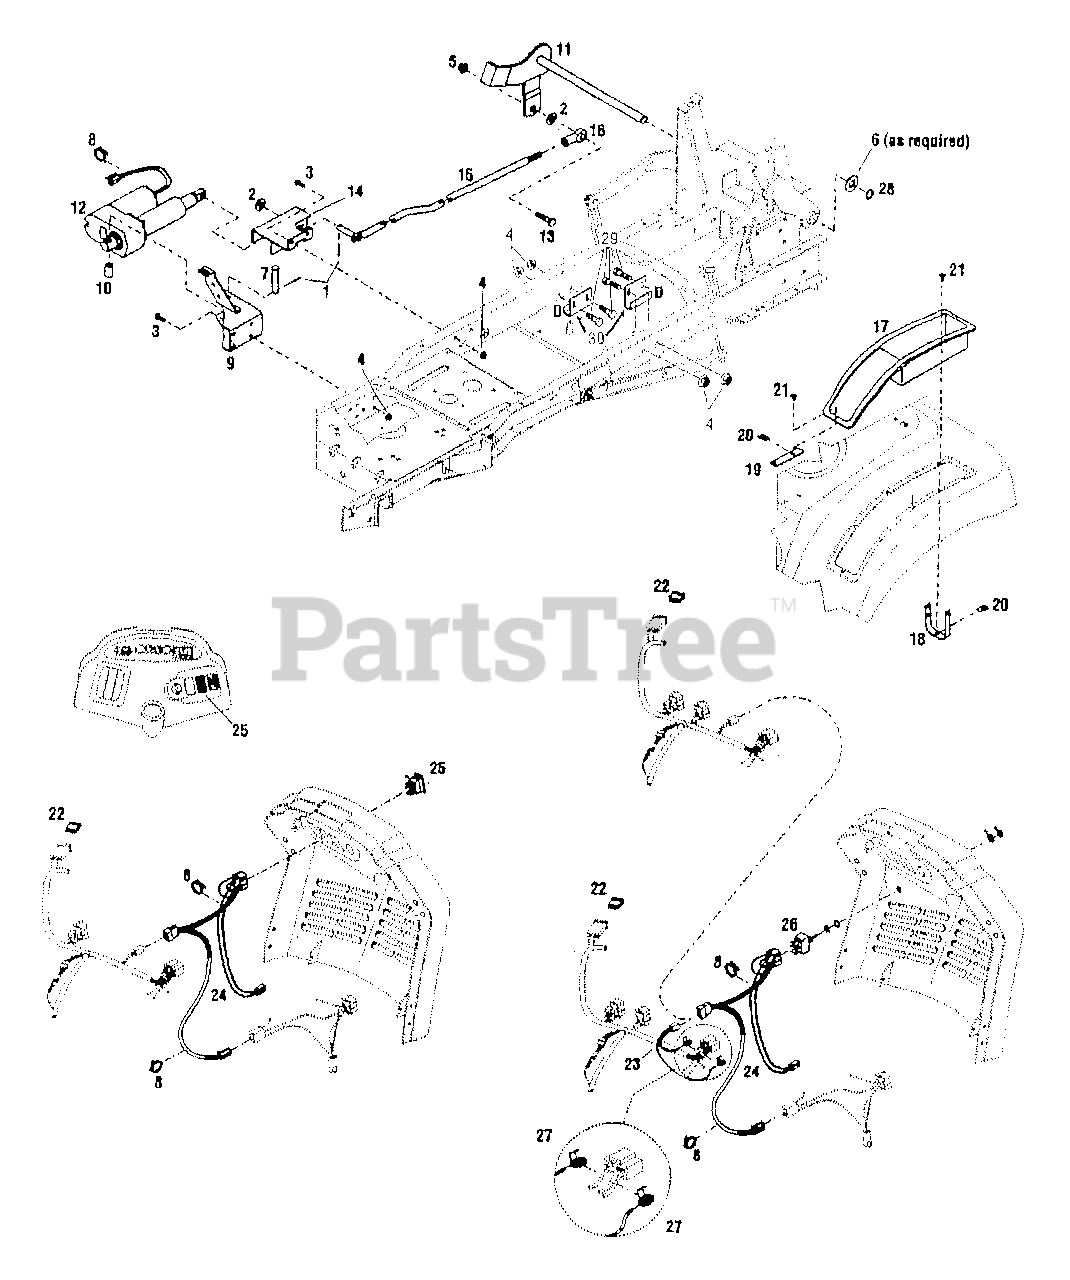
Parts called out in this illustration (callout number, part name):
1	PIN-COTTER .120X1.00 ZP
2	WASHER-1.06X.531X.1 ZP
3	SCR-HFLK 5/16-18X.75 ZP
4	NUT-HFLK 5/16-18 ZP
5	NUT-TOP LOCK 1/2-13 ZP
6	WASHER-1.25X.765X.049
7	PIN-CLEVIS .5X2.75
8	TIE-CABLE NYLON BLACK
9	SUPPORT-FRONT
11	PIVOT LIFT ARM ASSY.
13	SCR-SPECIAL 1/2-13X1 1/2
14	SUPPORT-REAR
15	ROD-LIFT
16	ROD-END
17	UTILITY BOX
18	RETAINER-UTILITY BOX
19	RETAINER-UTILITY BOX
20	SPEED NUT-1/4-20
21	SCR-1/4-20X5/8
22	FUSE-30 AMP
23	ADAPTER HARNESS
24	HARNESS-ACTUATOR
25	SWITCH-ROCKER
26	SWITCH-TOGGLE
27	CONNECTOR
28	RETAINING RING
29	SCR-HHC 5/16-18X.75 GR 5 ZP
30	STOP-MOWER DECK
